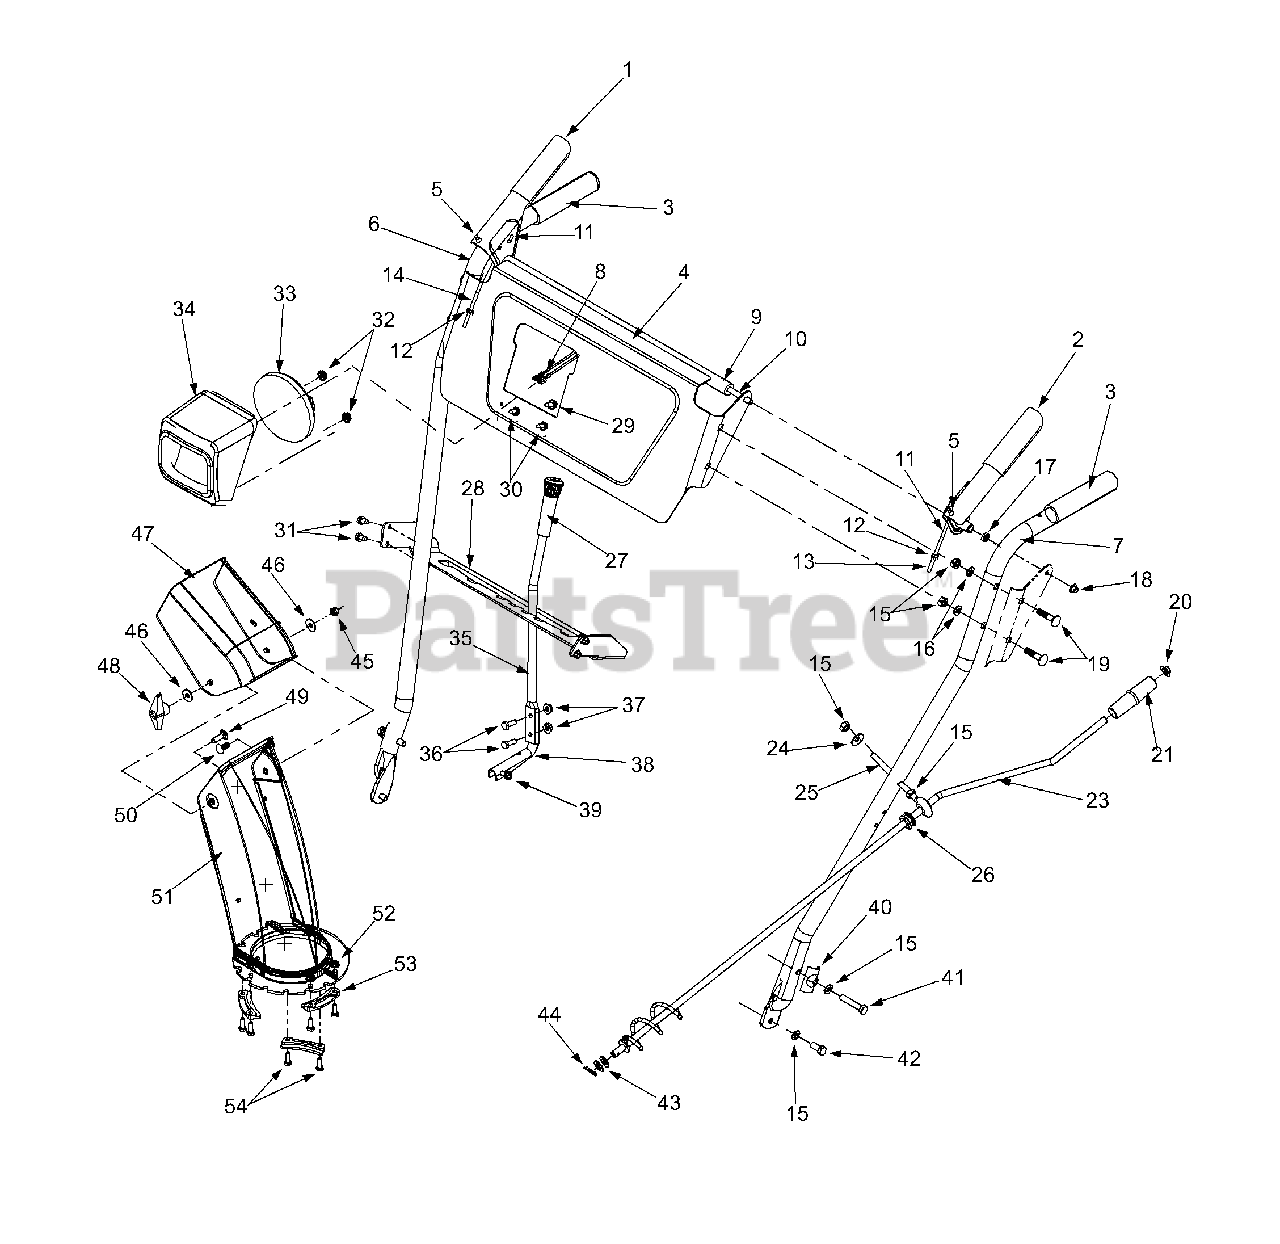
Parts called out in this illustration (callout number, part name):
1	Clutch Lever Assembly - RH
2	Clutch Lever Assembly - LH
5	Bumper Rubber
9	Pivot Rod Cover
10	Pivot Rod
11	"Z" Fitting
12	Hex Nut
13	Auger Clutch Cable
14	Drive Clutch Cable
15	Hex Nut 5/16-18
16	Lock Washer 5/16
17	Spacer
18	Nut Cap
19	Carriage Bolt 5/16-18 x 1.5
20	Push Rod Cap
21	Chute Crank Knob
23	Chute Crank Assembly
24	Bell Washer .340 ID x .873 OD
25	Eyebolt
26	Rubber Grommet
29	Hex Washer Screw 1/4-20 x .625
30	Hex Washer Screw #10 16 x .625
31	Hex Washer Screw 1/4-20 x .50
32	Hex Nut
33	Headlight 18 Watt
34	Headlight Cover
36	Hex Cap Screw 1/4-20 x .75
37	Hex Lock Nut 1/4-20
38	Shift Lever Support
39	Hex Washer
40	Handle Tab
41	Hex Cap Screw 5/16-18 x 1.75
42	Hex Cap Screw 5/16-18 x .75
43	Flat Washer 3/8 ID x .738 OD
44	Cotter Pin
45	Hex Lock Nut 5/16-18
46	Washer 5/16
47	Upper Chute
48	Knob 5/16-18
49	Carriage Screw 5/16-18 x 1.0
50	Carriage Bolt 5/16-18 x .75
51	Lower Chute
52	Hex Lock Nut 1/4-20
53	Chute Flange Keeper
54	Hex Cap Screw 1/4-20 x .75
